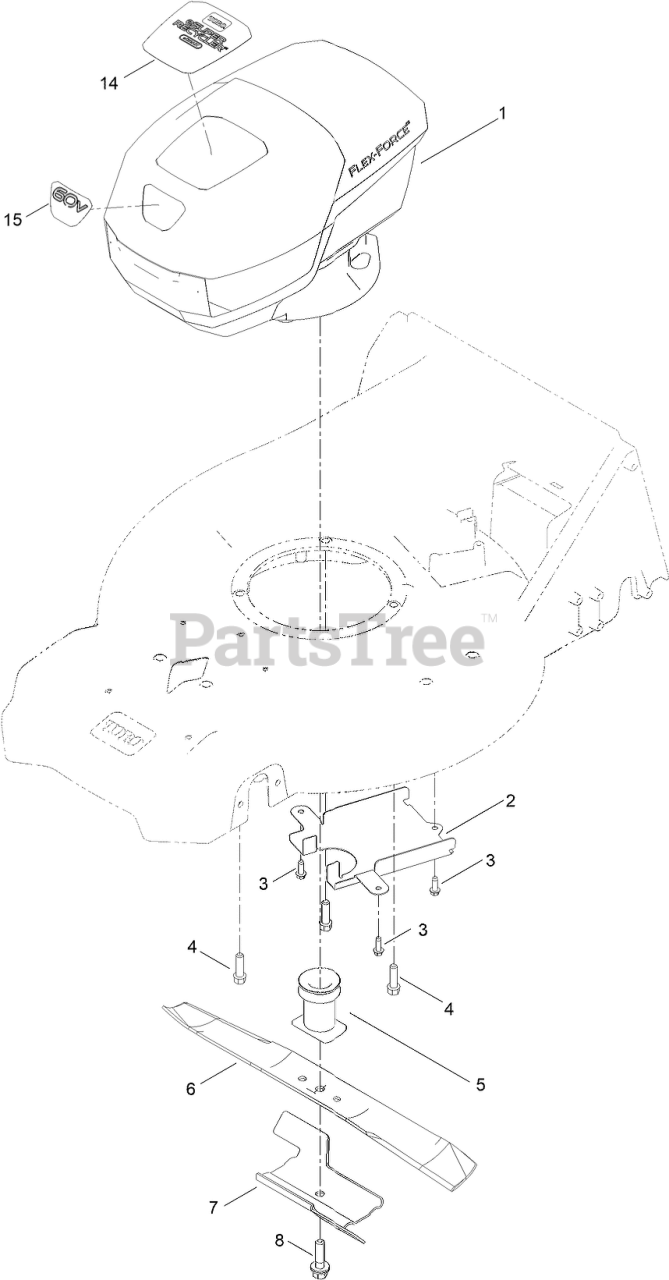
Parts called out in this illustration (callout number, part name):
1	MOTOR MODULE 60V
2	COVER-BELT, BOTTOM
3	SCREW-HWHTF
4	SCREW-TAPTITE
5	DRIVER-BLADE
6	BLADE-21IN, RECYCLING
7	ACCELERATOR-BLADE
8	BOLT-BLADE
14	DECAL-eC53AST, TOP
15	DECAL - 60V, FRONT
